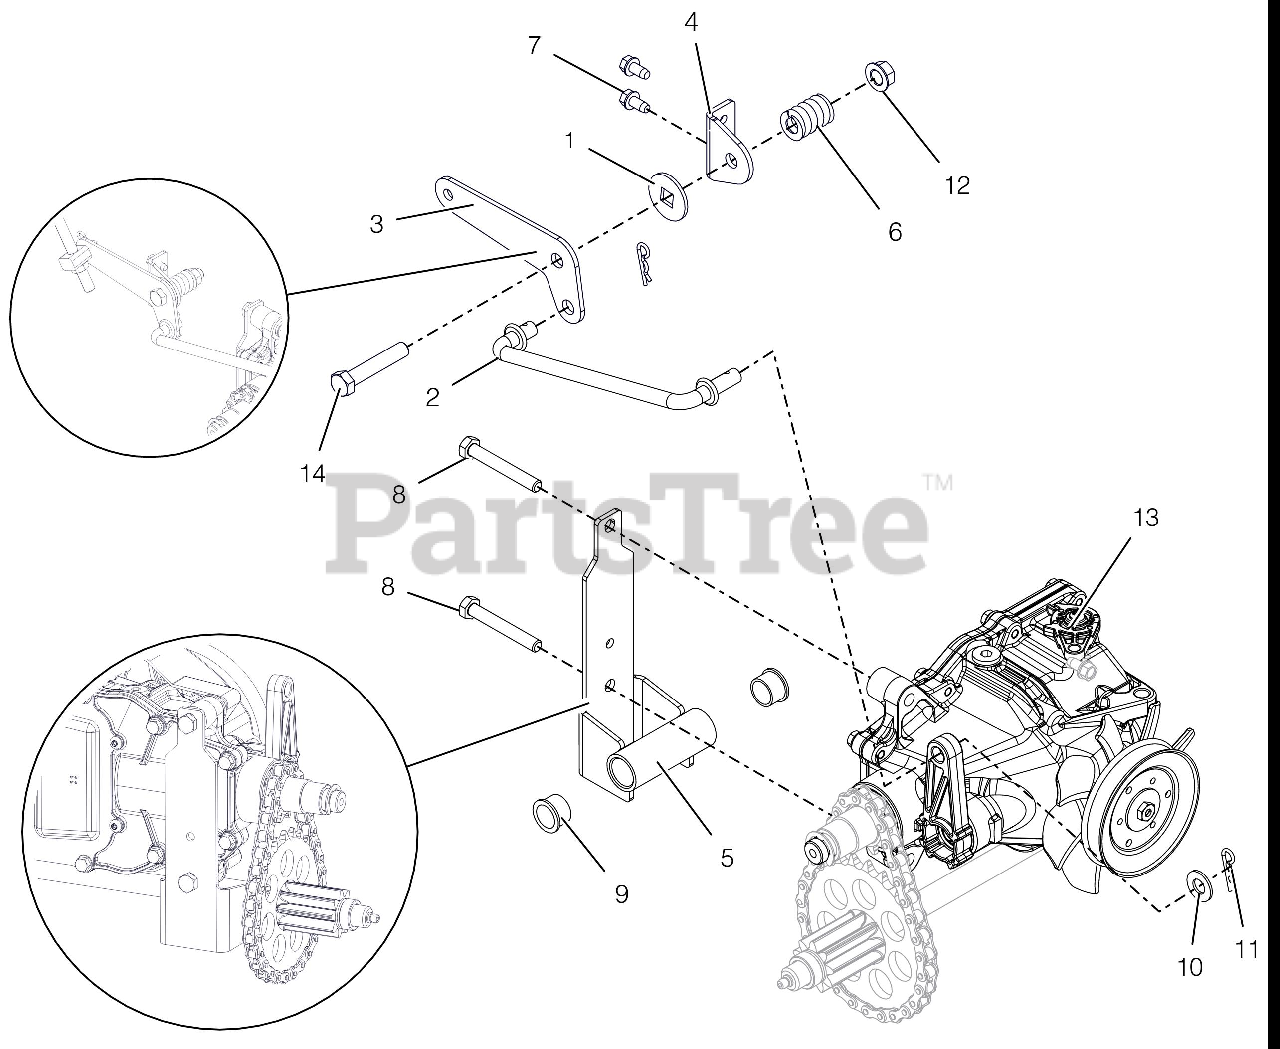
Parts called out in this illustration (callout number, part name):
1	FRICTION WASHER
2	ROD, HYDRO TRANS SHIFT
3	PIVOT, HYDRO TRANS SHIFT
4	BRACKET, HYDRO SHIFT PIVOT
5	TRANS MOUNT, TENSIONING, WHEEL
6	SG-COMP .187X.56X1.62
7	SCR-TAP .25-20X.50 HWH TR YWZ
8	@BLT-HEX .31-18X2.25 GR5 YWZC
9	BSHG-FLG .625X.750X.500X.875
10	@WSHR-FL-STL.406X.812X.065 YWZ
11	PIN-HAIR INT .08X.18X1.18 YWZC
12	@NUT-LK-TOP-FLG .38-16 YWZC
13	TRANSMISSION, HYDROSTATIC
14	@BLT-HEX .38-16X2.00 GR5 YWZC
